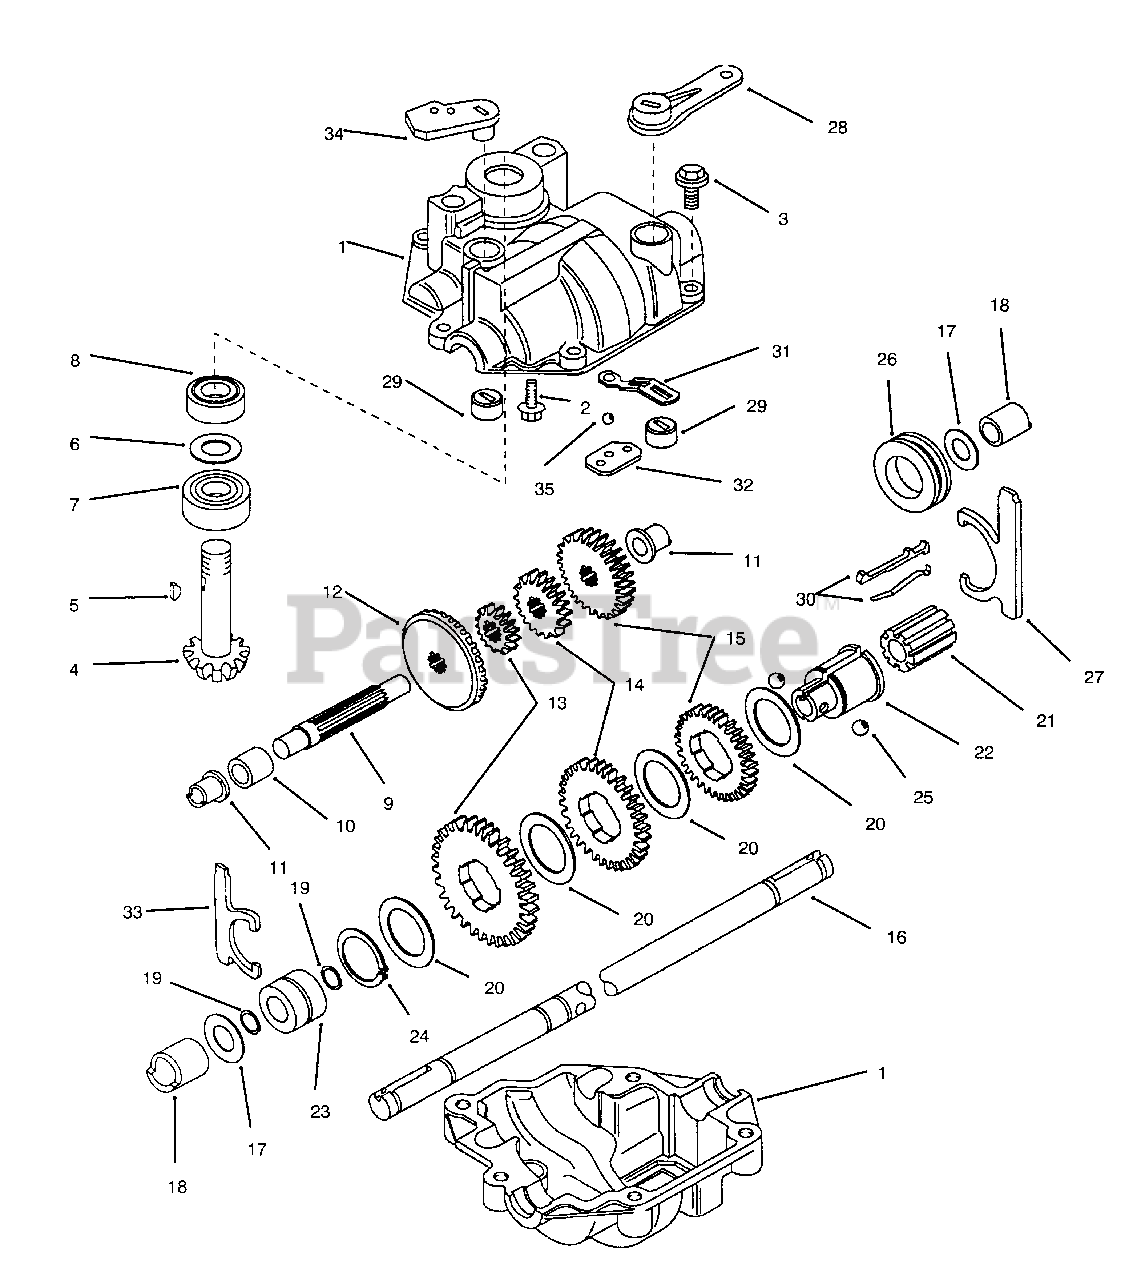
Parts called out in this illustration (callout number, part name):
1	Kit-Upper & Lower Case (Incl. Sealant)
2	Screw-Tapping
3	Screw-Tapping
4	Shaft-Input
5	Key-Woodruff
7	Bearing-Lower
8	Bearing-Upper
9	Kit-Shaft, Reduction (Incl. Ref. No.10-11)
11	Bushing Set
12	Ring Gear
13	Gear Set
14	Gear Set
15	Gear Set
16	Kit-Axle Shaft (Incl. Ref. No.17-19)
18	Bushing Set
19	Ring-Snap
21	Key-Holder,
22	Collar-Shift
24	Ring-Snap
25	Ball
26	Collar-Sliding
27	Fork-Shift
28	Arm-Shift
29	Support-Fork
30	Spring & Key-Shift
33	Fork-Clutch
34	Arm-Clutch
